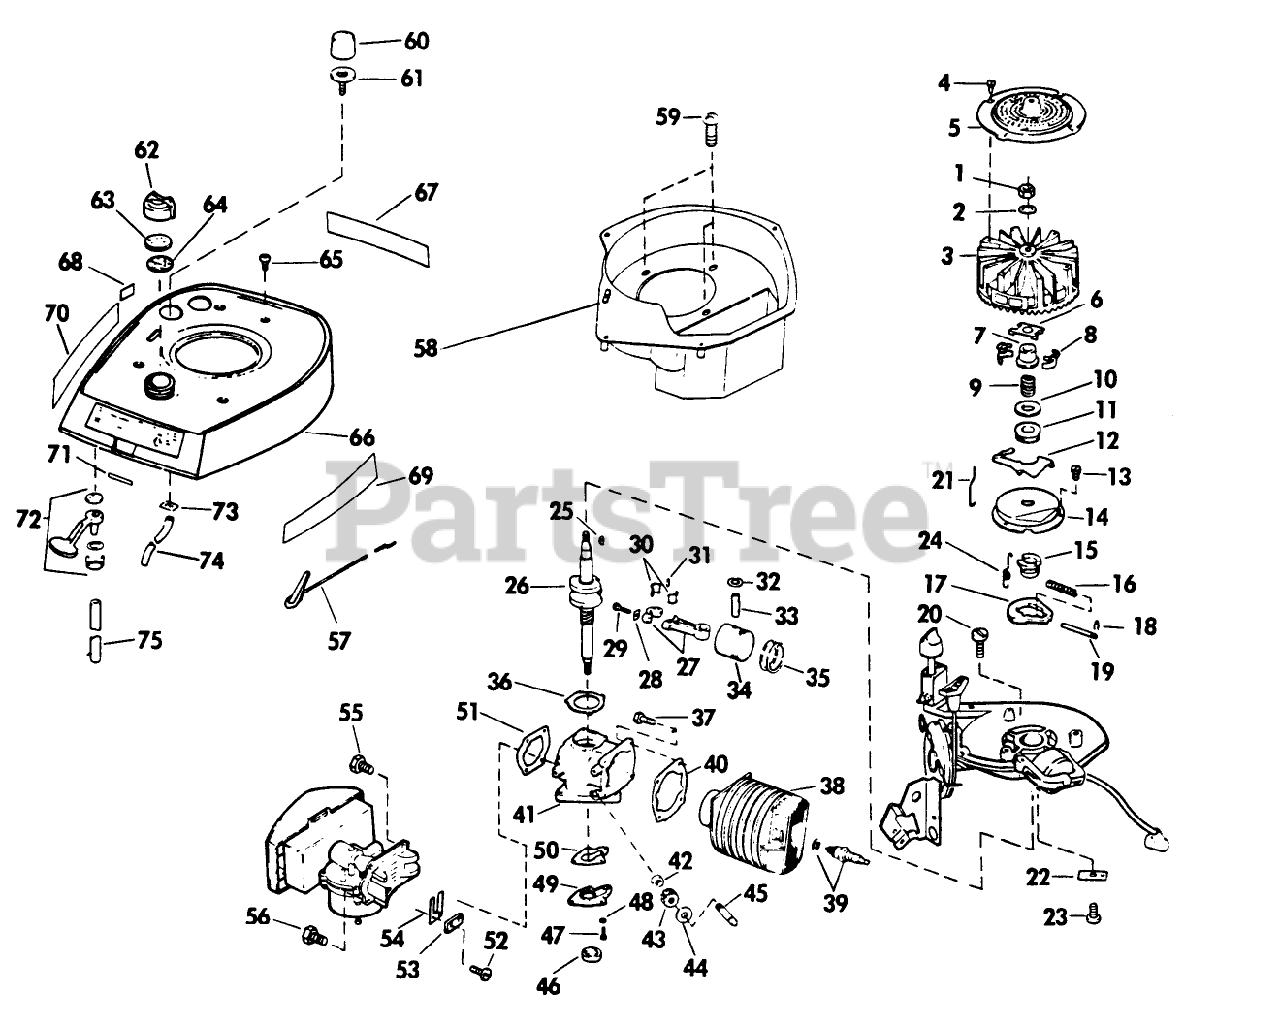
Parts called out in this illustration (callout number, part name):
1	NUT
4	SCREW F
5	FLYWHEEL SCREEN
6	YOKE S
7	COLLAR S
9	SPRING S
11	THRUST COLLAR S
12	LEVER-GOVERNOR S
13	SCREW S
14	DUST COVER S
15	SPARK ADV. S
16	SPARK ADV. SPRING S
17	FLYWEIGHT S
18	SPARK ADJ. SPRING
19	PIN,SPARK ADV. S
20	SCREW S
21	ROD S
22	TAB
23	SCREW S
25	KEY
29	SCREW
30	LINER ASM
32	RING-RETAINING
36	GASKET S
39	Spark Plug Gasket
40	GASKET S
42	SEAL S
43	GEAR, DR SHAFT S
44	THRUST WASHER
46	OIL SEAL
47	SCREW
49	GEAR COVER S
50	GASKET-CVR S
51	GASKET S
53	PLATE-BACKUP, REED
55	SCREW S
56	SCREW S
57	KNOB & ROD AY. S
63	GASKET S
64	BAFFLE - FOAM SM
65	SCREW S
71	SPRING BAR
73	LOCKNUT S
